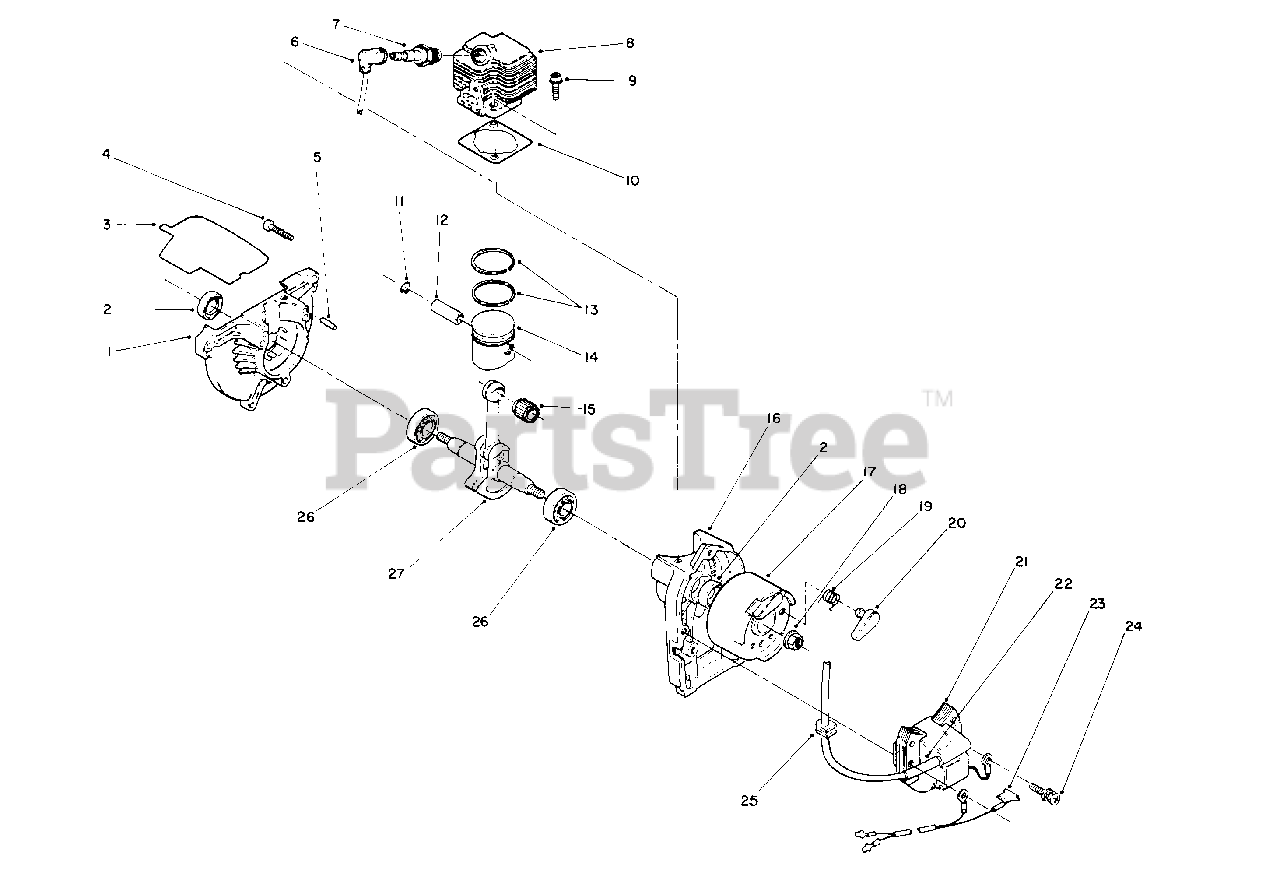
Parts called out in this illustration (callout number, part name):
1	Case-Drive
2	Seal-Oil
3	Gasket-Baffle
4	Screw-Pan Hd.
5	Pin-Dowel
6	Boot-plug
7	Plug-Spark
8	Cylinder
9	Bolt-Cylinder
10	Gasket-Cylinder
11	Clip-Piston Pin
12	Pin-Piston
13	Ring-Top
14	Piston (Incl. Ref. #11 & 12)
15	Bearing-Needle
16	Case-Starter
17	Flywheel (Incl. Ref. #19 & 20)
18	Nut-Conical
19	Spring-Return
21	Coil-Ignition
23	Lead-wire
24	Bolt/Washer
26	Bearing-Main
27	Crank Shaft Assembly
